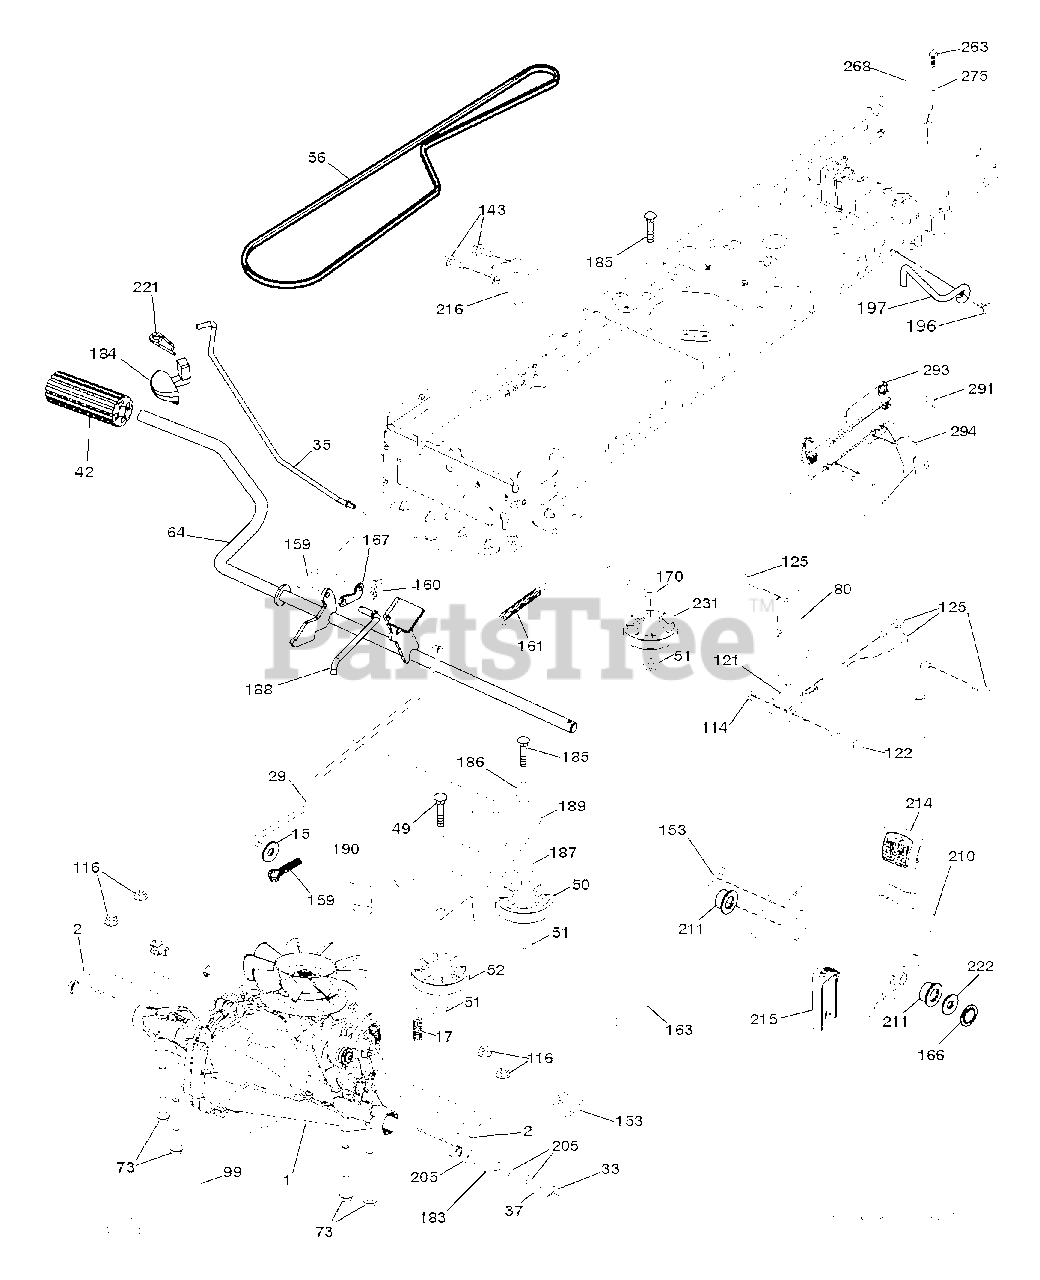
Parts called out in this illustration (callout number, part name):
2	SQUARE KEY
17	SPRING.BRAKE.HG3000/3500
29	ROD BRAKE
33	E-RING LT
35	ROD, BRAKE, PARK
42	PEDAL COVER T
49	BOLT
50	IDLER.FLAT.910.OFFSET
51	NUT LOCK FLG 3/8-16 UNC
52	IDLER.V-GROOVE.910.OFFSET
64	SHAFT.ASM.PEDAL.BRK.CNTR
73	BOLT HEX 5/16-18 GR 5
80	STRAP.TORQUE.FS.T2
99	ROD.ASM.BYPASS.SPRING.T2.FS
114	NUT.71038.31-18.HEX.NYLOCK
116	NUT LOCK HEX FLANGE 5/16-18
121	BRACKET STRAP TORQUE
122	BOLT.5/16-18X2.5
125	SCREW
153	RETAINER M
159	COTTER PIN
160	RETAINER CLIP
161	SPRING, RETURN LT
163	ROD.CONTROL.PCH.T2.TEX
166	NUT.PUSH.625
167	LATCH.BRAKE.SPRING
170	KEEPER.CENTER SPAN.1.688
183	SPACER, AXLE PVST
184	HANDLE.PARKING.BRK.PRED.LT.RED
186	SPACER.RETAINER
187	WASHER 12/32X2X10GA
188	LINK.CLUTCH.GROUND.DRIVE
189	BELLCRANK.GROUND.DRIVE.TEX.
190	KEEPER.BELLCRANK.DRIVE
196	SCREW 3/8-16X1
197	LINK.CLUTCH.ANIT-ROTAT
210	ROCKER.ASM.PEDAL.CONTR
211	BEARING.NYLON
214	PAD PEDAL FORWARD
215	PEDAL.REVERSE.TEX.GT.4
216	BRACKET.PULLEY.IDLER.W/TEX
221	RETAINER.SPRING.CLIP.H
222	WASHER 21/32 X 1-1/4 X 10 GA.
231	IDLER.V-GROOVE.1.688.OFFSET
263	SCREW, 3/8-16X3/4
275	WASHER
291	SHOULDER BOLT 5/16-18TT
